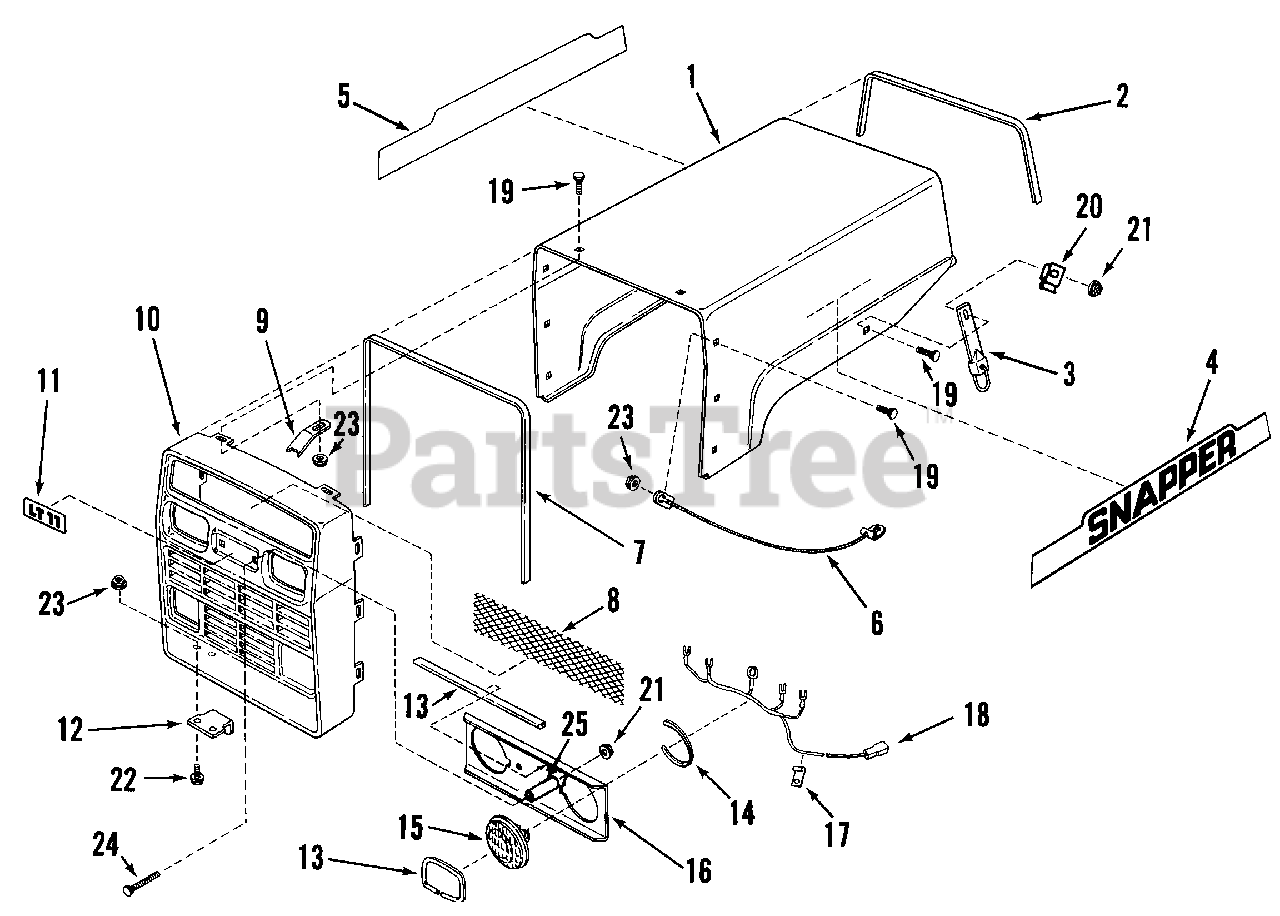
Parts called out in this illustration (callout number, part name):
1	HOOD, LT11 Series Tractor
2	TRIM, Rear Edge Hood
3	LATCH, Hood Retaining
4	DECAL, SNAPPER (Left Side)
5	DECAL, SNAPPER (Right Side)
6	CABLE, Hood Stop
7	GASKET, Grille
8	MESH, Grille
9	RETAINER, Grille Mesh
11	DECAL, LT11
12	HINGE, Hood
13	GASKET, Head Lamp
14	GASKET, Head Lamp to Bracket
15	HEAD LAMP
16	BRACKET, Head Lamp
17	CLIP, Wiring Harness
18	HARNESS, Head Lamp Wiring
19	BOLT, 1/4-20 x 5/8" Flat Head Carriage
20	CLIP, Hood Retainer
21	NUT, 1/4-20 Hex Flange Lock, Grade 5
22	BOLT, 1/4-20 x 1/2" Hex Flange Lock, Grade 5
23	NUT, 1/4-20 Hex Flange Lock, Grade 5
24	BOLT, 1/4-20 x 2" Flat Head Carriage
